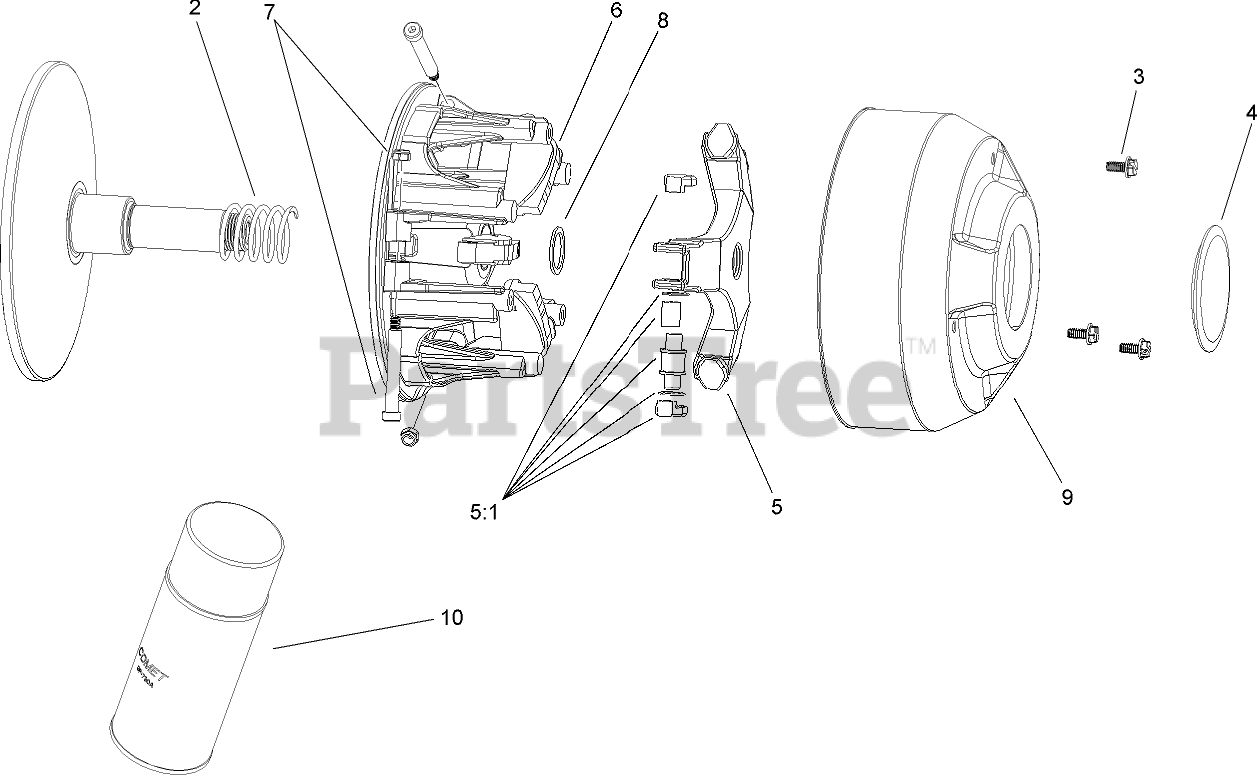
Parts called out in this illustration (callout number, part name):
2	SPRING
3	SCREW-HHF
5	SPIDER ASM
5:1	SPIDER REPLACEMENT PARTS KIT
6	ARM-CAM
7	PIVOT BOLT AND NUT KIT
8	SPACER
9	COVER
10	LUBRICANT-DRY
